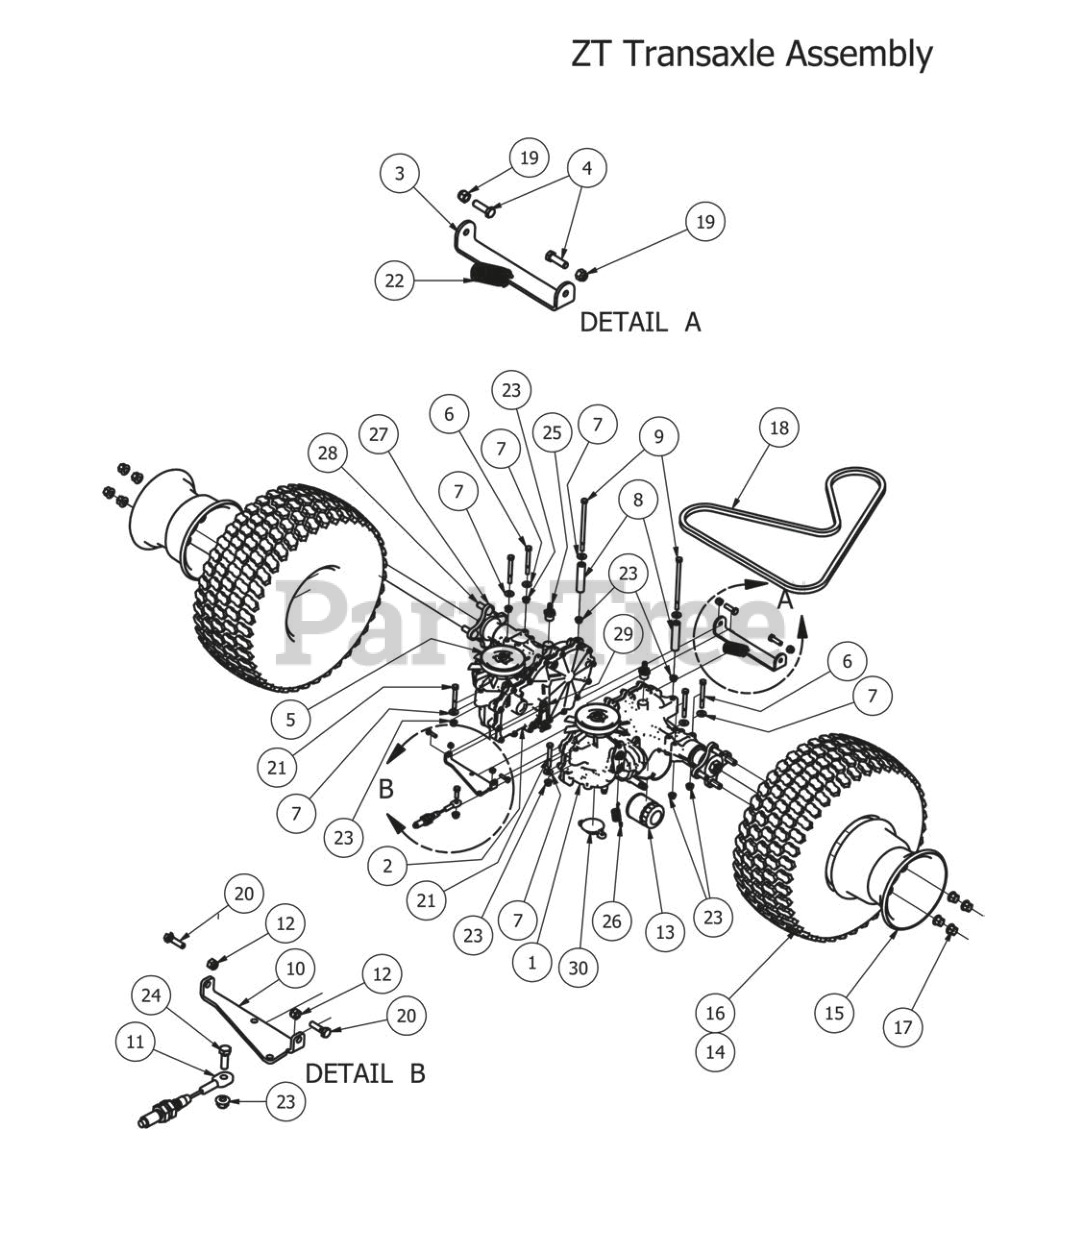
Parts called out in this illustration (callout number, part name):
1	Left ZT Transaxle
2	Right ZT Transaxle
3	Crossover Bar for ZT
4	3/8" x2" Hex Bolt
5	Fan/Pulley Kit
6	5/16" x 3" Hex Bolt
7	5/16" Flat Washer
8	3 1/4" Spacer
9	5/16" x 6" Bolt
10	ZT Crossover Brake Bracket
11	Brake Cable Stand On
12	1/4" Nylock Nut
13	Transaxle Filter
14	20 x 10.5-8 Tire/Wheel Assy
15	8 Inch Wheel
16	20X10-8 Turf Tire
17	Acorn Lug Nut
19	3/8 Nylock Nut
20	1/4-20 x 1 GR 5 hex bolt zinc
21	5/16" x 2 1/2" Bolt
23	5/16" Nylon Flange Nut
24	5/16" x 1" Bolt
25	45 degree fitting
26	Transaxle Spring
27	ZT Transaxle Hub
28	Transaxle Wheel Studs
29	Transaxle Brake Lever
30	ZT Transaxle Charge Plate/With O'Ring
